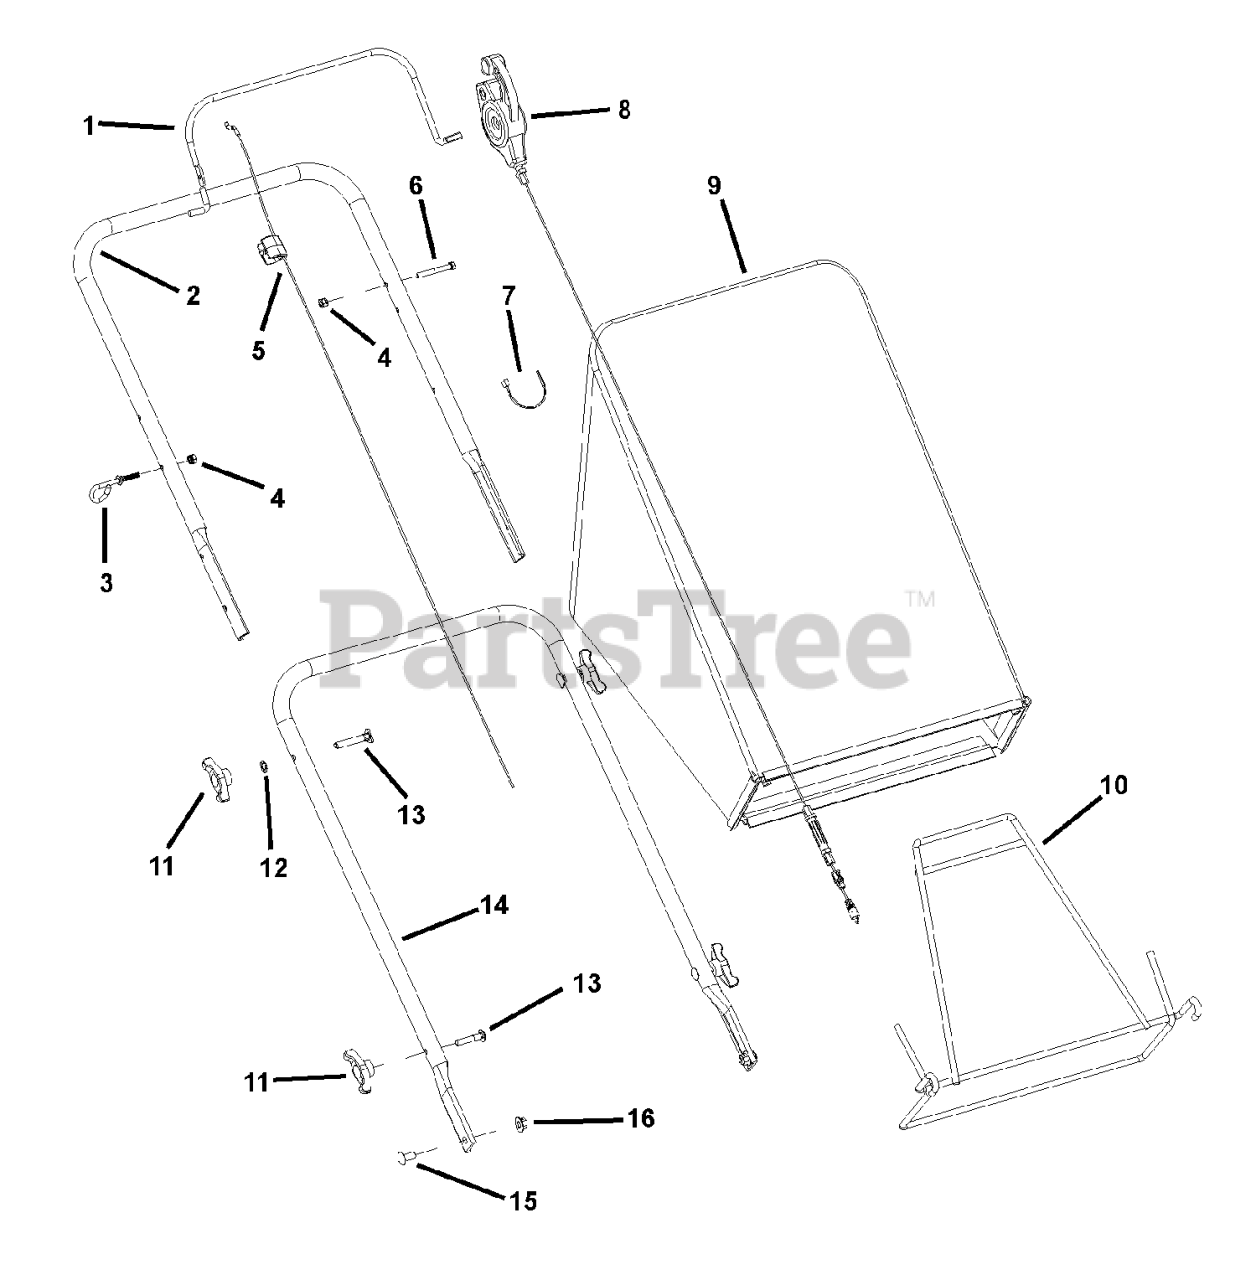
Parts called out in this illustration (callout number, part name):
1	BAIL, OPC Propelled
2	HANDLE, Upper
3	GUIDE, Rope (1/4-20 thread)
4	NUT, Hex, 1/4-20
5	CABLE, Bail
6	BOLT, Hex 1/4-20 x 2
7	WIRE TIE
8	CONTROL, Drive, Single Speed
9	BAG, Cloth
10	FRAME, Grass Bag
11	KNOB, Wing, 5/16-18
12	LOCKWASHER, 5/16
13	BOLT, 5/16-18 x 2, GR2
14	HANDLE, Lower
15	BOLT, 5/16-18 x 3/4, GR5
16	NUT, Hex, 5/16-18
